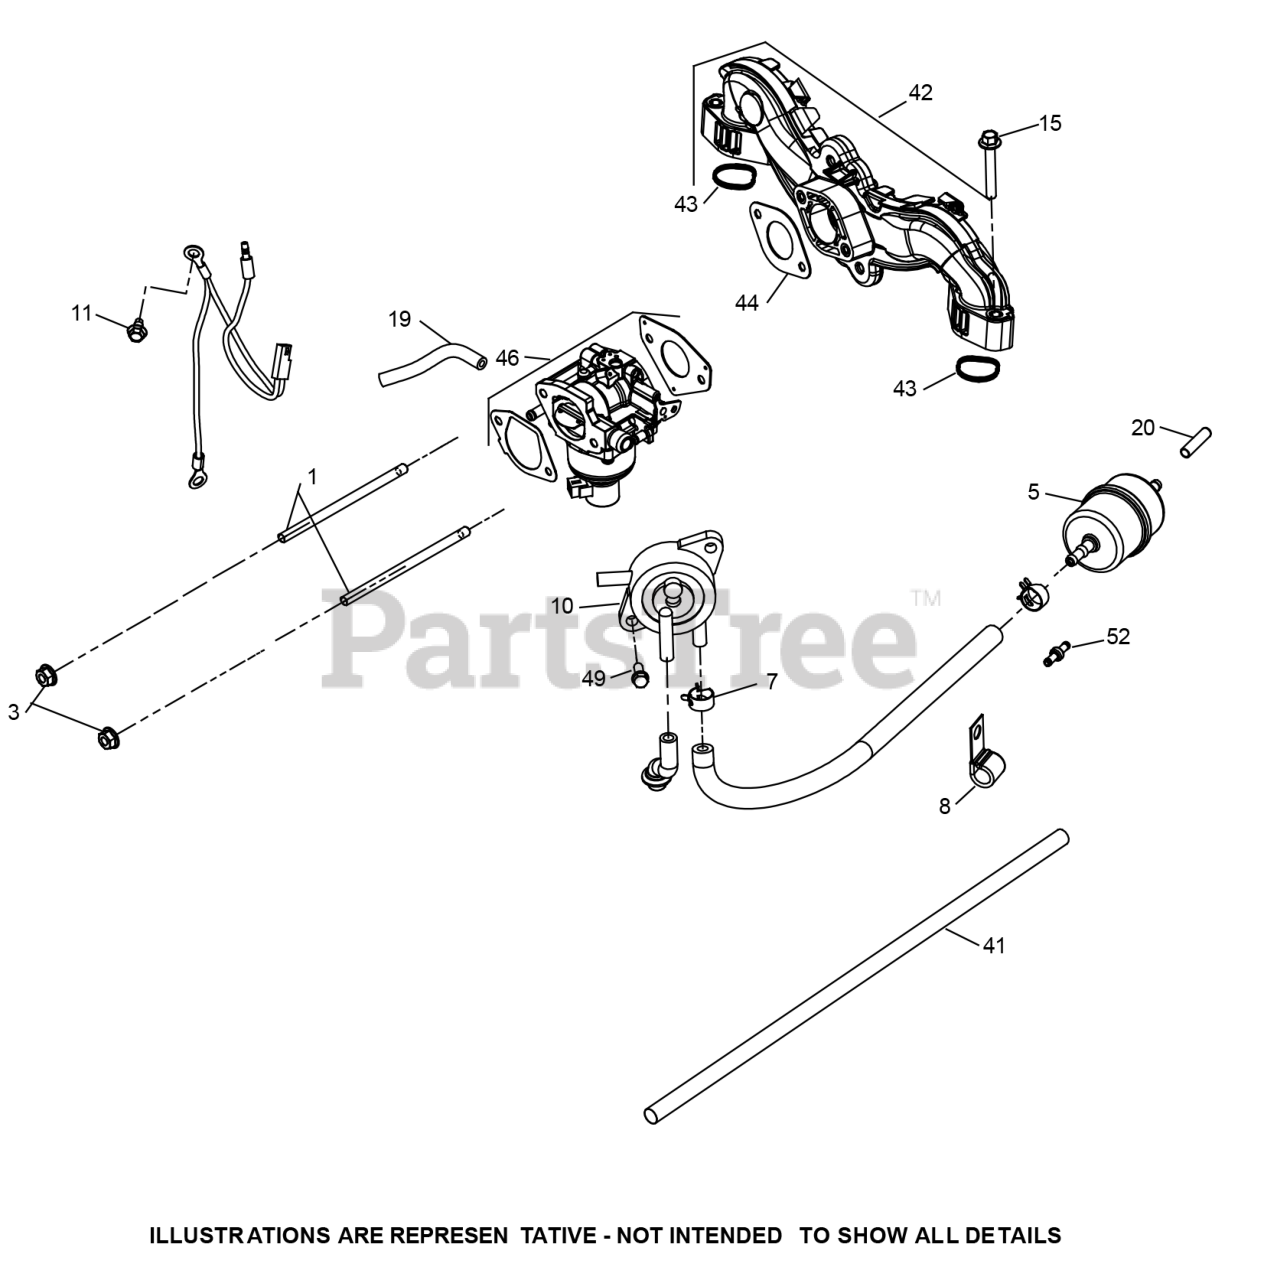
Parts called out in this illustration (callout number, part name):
1	CARB MOUNTING STUD
3	HEX FLANGE NUT
8	CLIP
15	HEX SCREW FLANGE
19	EVAPORATIVE HOSE
41	SLEEVE-ANTI ABRASION
42	INTAKE MANIFOLD W/GASKETS
43	O-RING, INTAKE PORT
44	GASKET, CARBURETOR (PIM, CV)
46	CARBURETOR KIT NIKKI
49	HEX HEAD SCREW
